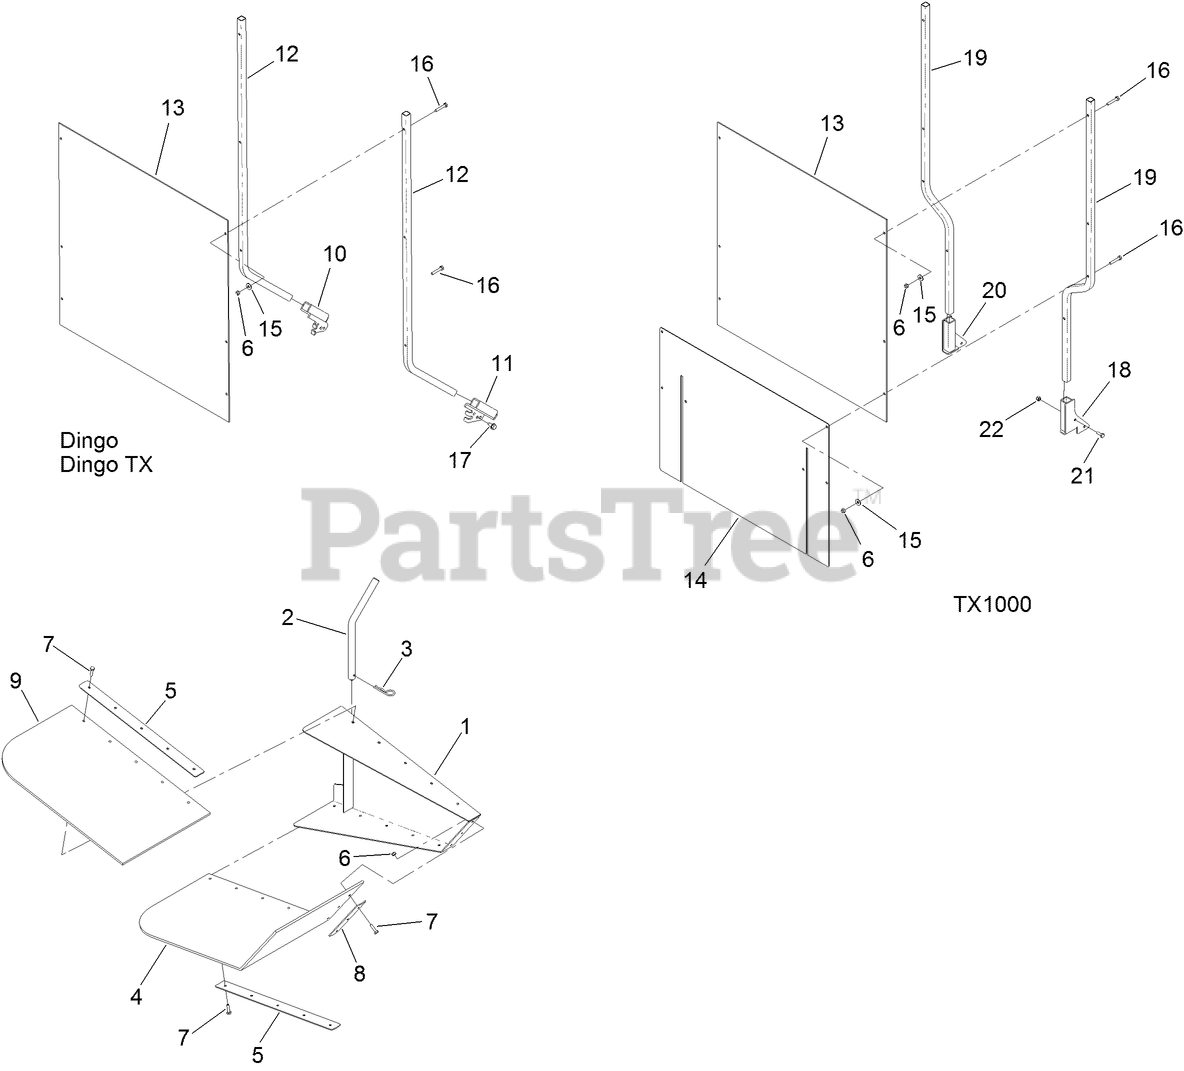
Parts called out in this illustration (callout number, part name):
1	CHIPPER GUARD ASM
2	PIN-HINGE
3	PIN-HAIR
4	GUARD-SKIRT, REAR
5	CLAMP-SKIRT
6	NUT-HEX
7	SCREW-HH
8	CLAMP-SKIRT
9	GUARD-SKIRT, FRONT
10	BRACKET-SUPPORT, RH
11	BRACKET-SUPPORT, LH
12	SUPPORT-SHIELD
13	SHIELD-LEXAN
14	SKIRT-PROTECTOR
15	WASHER-FLAT
16	SCREW-HH
17	SCREW-HWHTF
18	BRACKET-SUPPORT, LH
19	SUPPORT-TUBE, SHIELD
20	BRACKET-SUPPORT, RH
21	SCREW-HH
22	NUT-LOCK, NI
